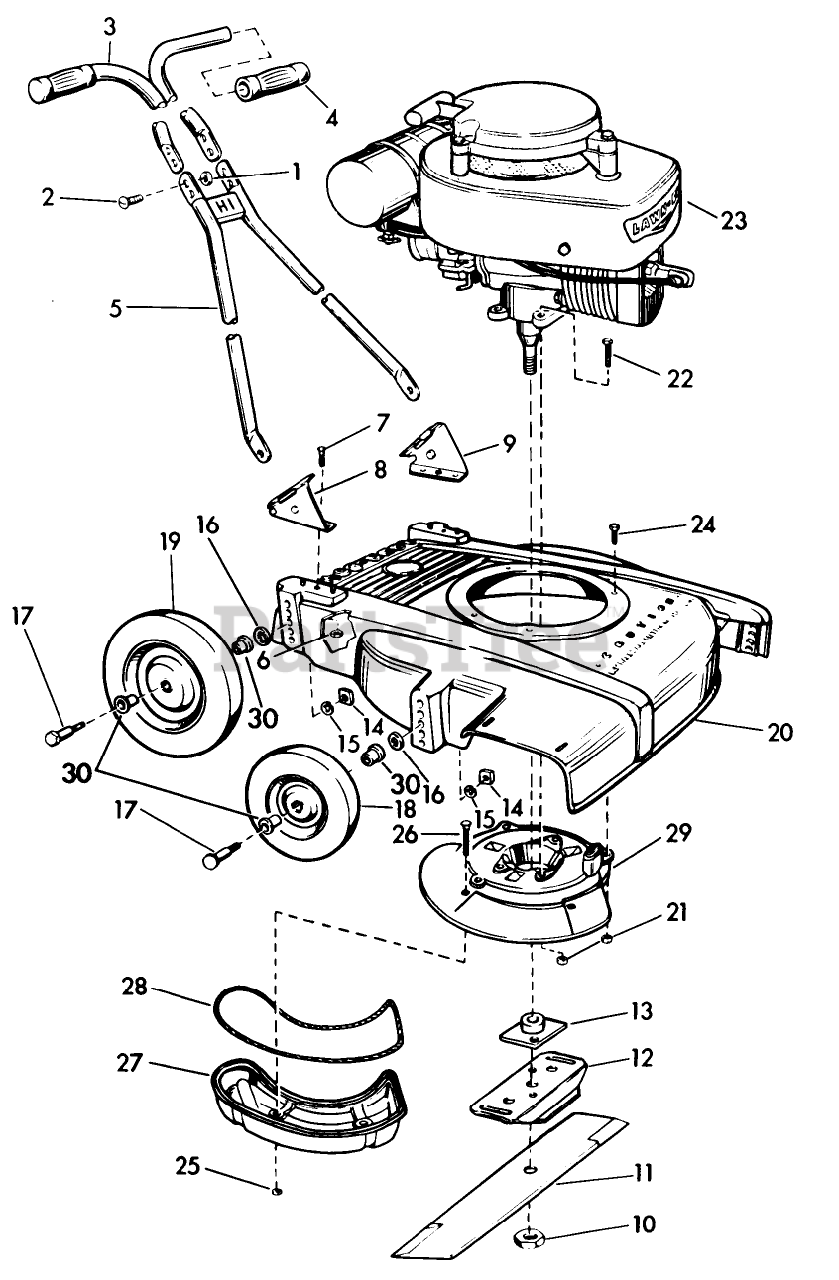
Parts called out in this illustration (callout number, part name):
1	STOP NUT
10	NUT-BLADE
13	PLATE AND COLLAR ASM
15	WASHER, LOCK
20	Housing-18"
25	LOCKNUT E
